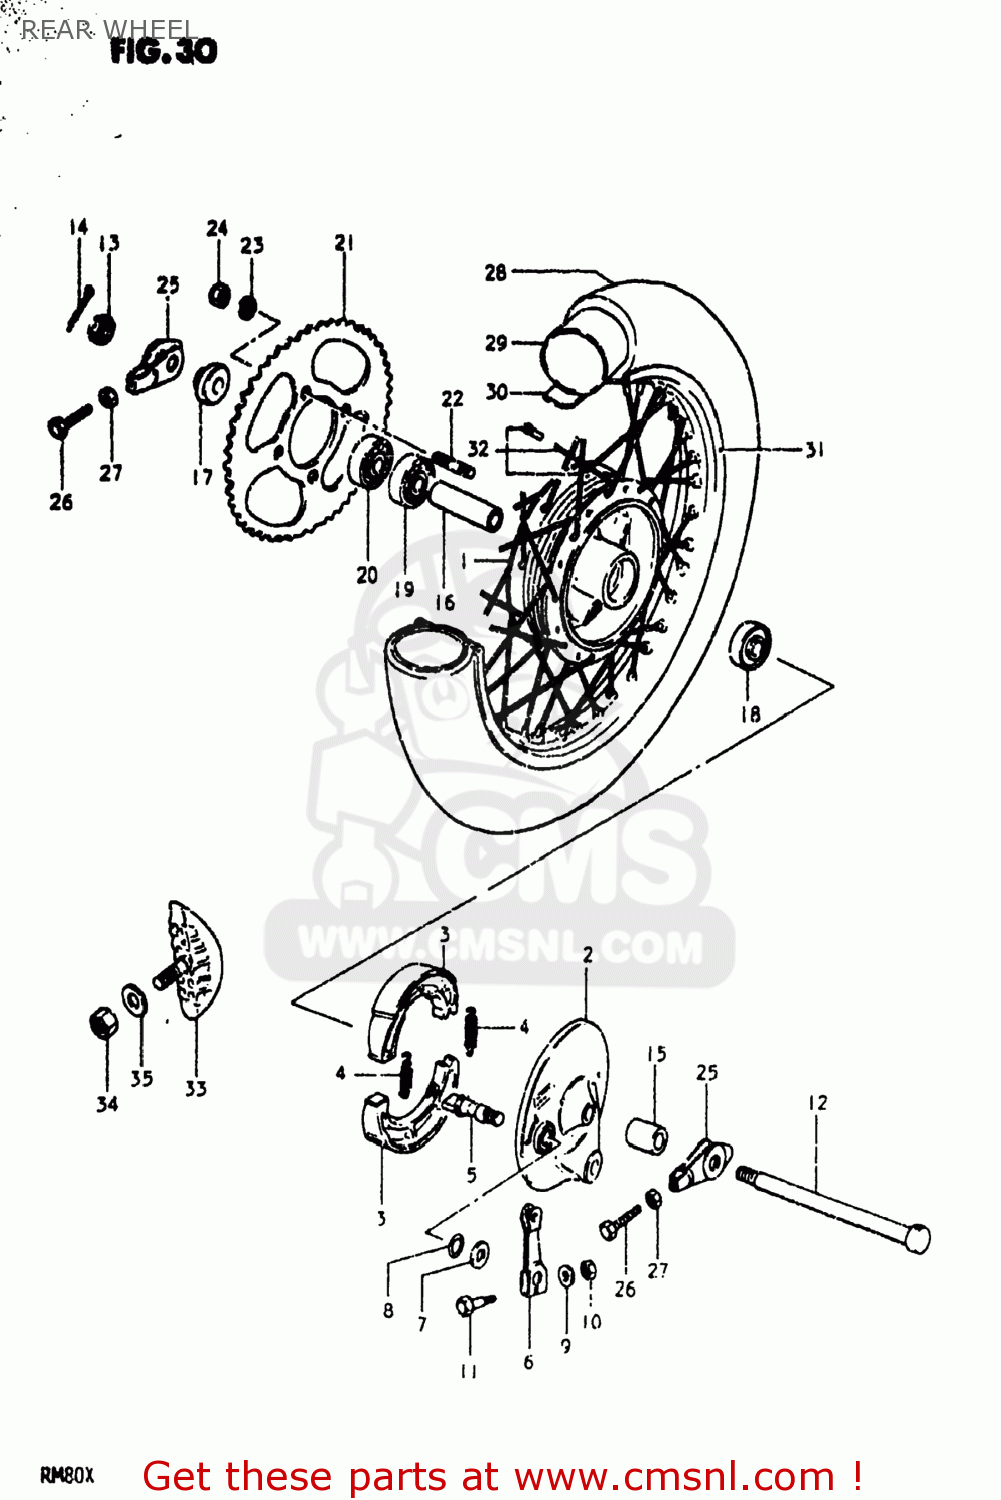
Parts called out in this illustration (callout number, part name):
1	DRUM SET,REAR HUB
2	PANEL,REAR BRAKE ANCHOR
3	SHOE,BRAKE (MCA)
4	SPRING(L:34)
5	CAM,FRONT BRAKE
6	LEVER,RR BRAKE CAM
7	WASHER (14.5X22X1.6)
8	O-RING (D:2.4 ID:13.8)
9	WASHER
10	NUT
11	BOLT(6X33)
12	AXLE,REAR
13	NUT 12MM
14	COTTER PIN
15	SPACER (12.1X22X27)
16	SPACER (12.6X19X79)
17	SPACER,RR AXLE,L
18	BEARING
19	BEARING
20	BEARING
21	SPROCKET,REAR
22	BOLT
23	LOCK WASHER
24	NUT
25	ADJUSTER,CHAIN
26	BOLT(6X38)
27	NUT
28	TIRE
29	TUBE ASSEMBLY,WHEEL,INNER
30	PROTECTOR,INNER TUBE
31	RIM,REAR WHEEL
32	SPOKE ASSY,RR WHEEL
33	STOPPER,BEAD
34	NUT
35	WASHER
